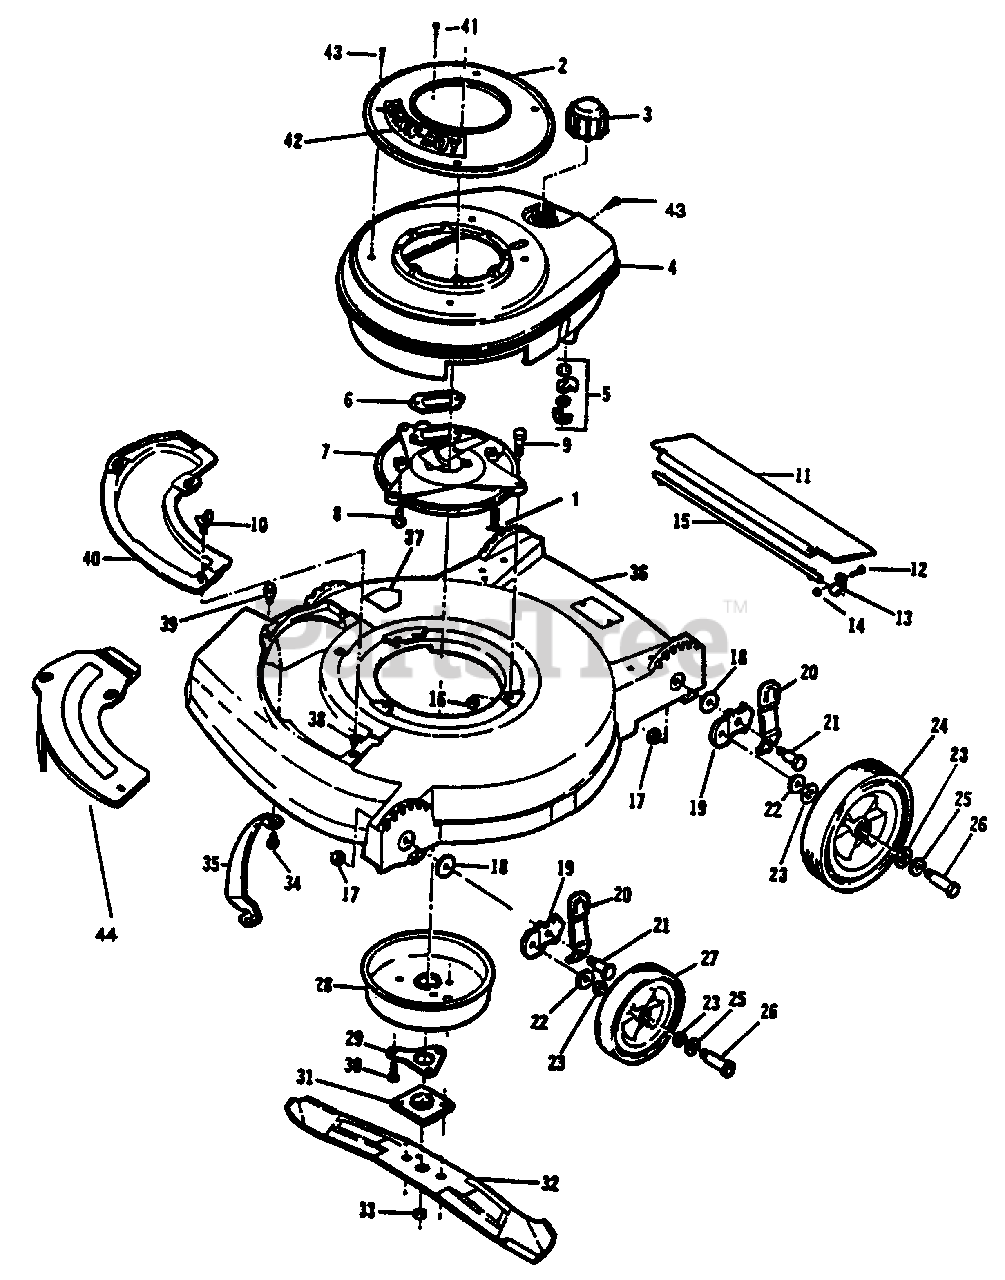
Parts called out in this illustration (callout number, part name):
1	Screw
2	Starter Base
3	Fuel Cap
4	Shroud-Engine (Inc. 5)
5	Fuel Shut on Assembly
6	Gasket-Exhaust
7	Plate-Muffler
8	Screw-Muffler Pit. to Block
9	Screw-Muffler Pit. to Hsg.
10	Wing Screw
11	Shield-Trailing
12	Screw-Trailing Shield
13	Clamp
14	Nut
15	Rod-Trailing Shied
16	Nut-Muffler Pit. to Hsg.
17	Nut-Wheel Ht. Adjust
18	Washer-Wheel Ht. Adjust
19	Bracket-Wheel Ht. Adjust
20	Knob & Spring Assembly
21	Bolt-Shoulder
22	Washer
23	Washer-Felt
24	Wheel-Rear
25	Washer-Wheel Bolt
26	Bolt-Wheel
27	Wheel-Front
28	Muffler Cover Assembly
29	Support-Crankshaft
30	Screw-Muff. to Muff. Plate
31	Collar & Plate Assembly
32	Blade 19"
33	Nut
34	Screw
35	Toe Bar
36	Housing Assembly (Inc. 37-38)
37	Decal-Blade Contact Warning
38	Grommet
39	Screw-Plate Mounting
40	Cover Plate
41	Screw-Starter Mounting
42	Applique
43	Screw-Shroud
44	Mulch Plate Accessory
